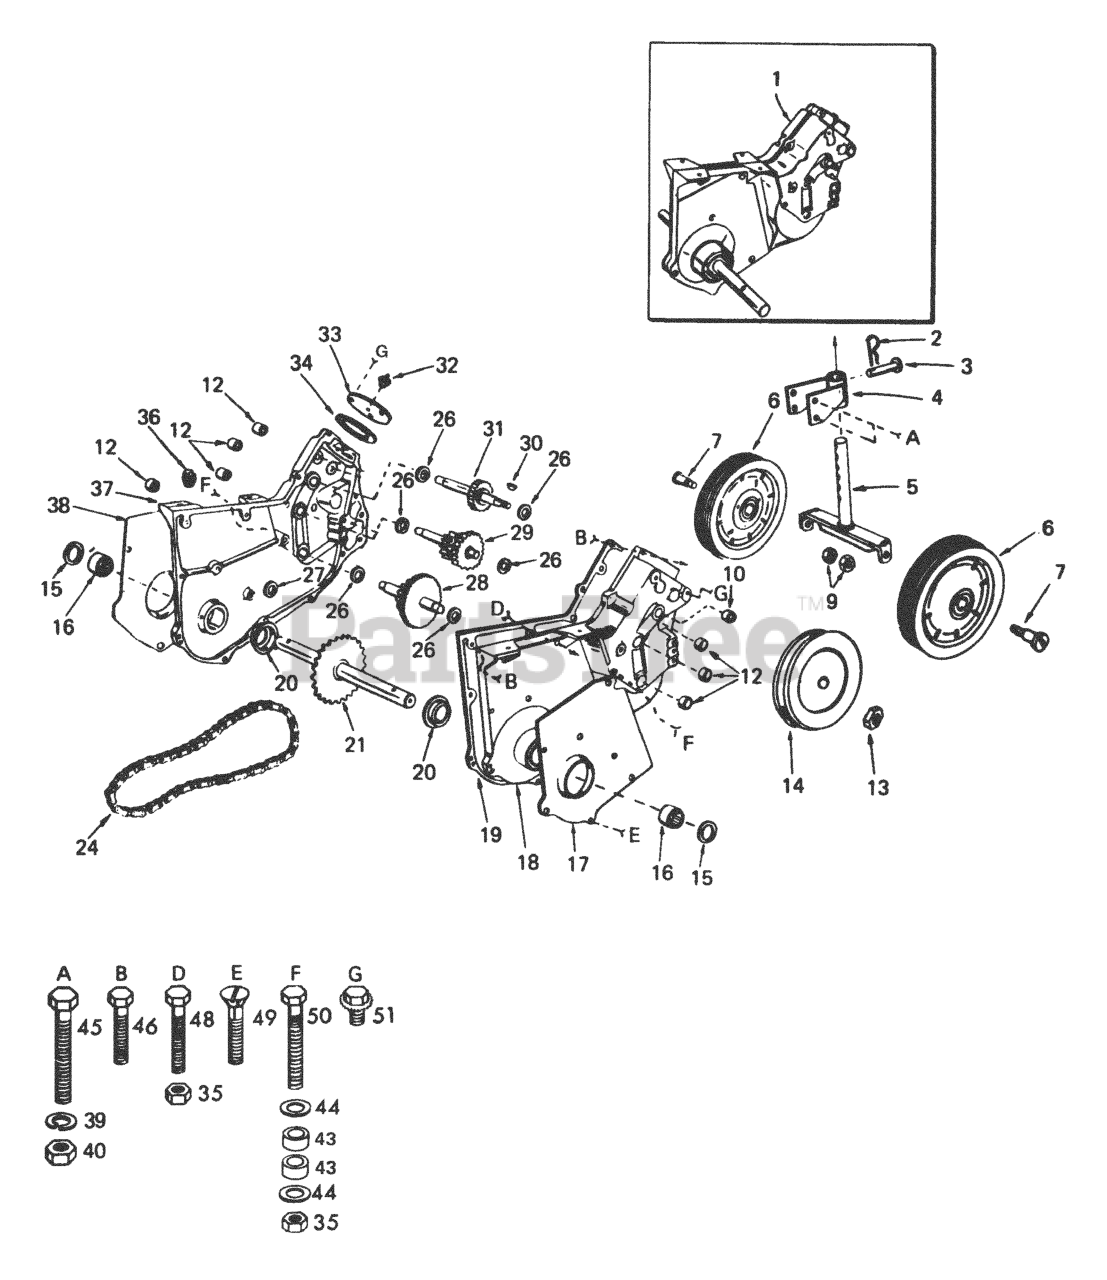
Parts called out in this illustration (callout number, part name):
1	Transmission
2	Retainer Spring
3	Drilled Pan Head Rivet 3/8 x 1-3/4
4	Gauge Wheel Sleeve and Brackets
5	Gauge Wheel Adjusting Shaft and Bracket
7	Shoulder Bolt
9	Locknut 3/8-16 UNC Nylock
10	Needle Bearing
12	Needle Bearing
13	Locknut 1/2-20 UNF
14	Input Sheave
15	Oil Seal
16	Needle Bearing
17	Gear Case Shield L.H.
18	Gear Case and Bearings L.H. Half
20	Thrust Cap
21	Tine Shaft and Sprocket
24	Roller Chain
26	Thrust Washer
28	2nd Reduction Shaft and Gears
29	1st Reduction Shaft and Gears
30	Woodruff Key 3/16 x 5/8
31	Input Shaft and Pinion
32	Relief Valve
33	Gear Shift Cover
34	Gasket
35	Locknut 5/16-18 UNC
36	Pipe Plug 1/2-14 N.P.T.
37	Gear Case and Bearings R.H. Half
38	Gear Case Shield R.H.
39	Washer Lock 3/8
40	Hex Nut 3/8-16 UNC
44	Washer 11/32 x 11/16 x 16 Ga.
45	Hex Bolt 3/8-16 x 2-1/4
46	Hex Hd. Roll-Lok Thd. Forming Screw 5/16-18 x 1-1/2
48	Hex Bolt 5/16-18 x 2
49	Flat Hd. Slotted Roll-Lok Thd. Forming Screws 5/16-18 x 3/4
50	Hex Bolt 5/16-18 x 6 Gr. 5
51	Screw Mach. Hex Hd. 5/16-18 x 3/4
